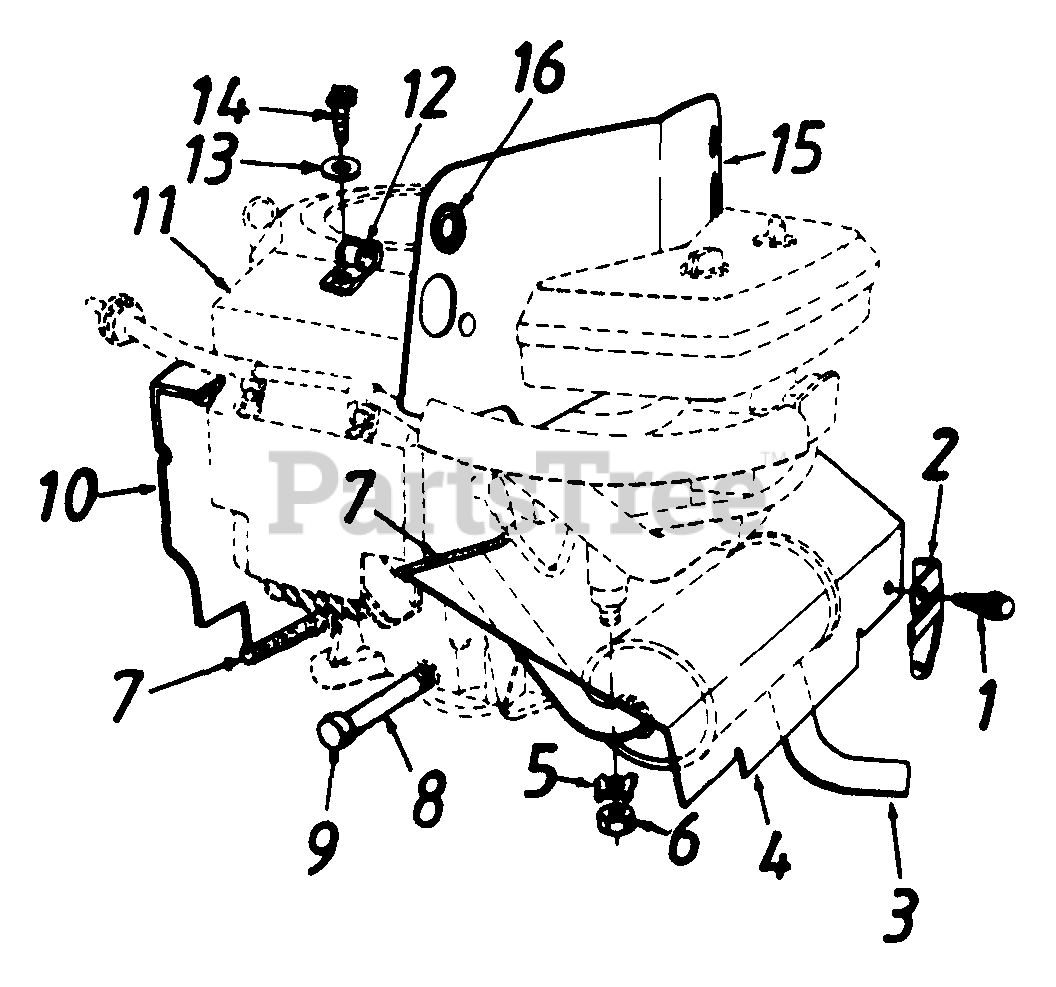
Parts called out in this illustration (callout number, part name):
1	Hex AB-Tap Scr. 1/4 x .62"
3	Muffler
4	Front Heat Shield
5	Spec. L-Wash. 5/16 x .88"
6	Hex Nut 5/16-18 Thd.
7	Trim Strip 12" Lg.
8	Pipe Nipple
9	Oil Drain Cap
10	Rear Baffle (Used on Styles 5, 8 and 9)
11	Engine
12	Clamp
13	Fl-Wash. .188" I.D. x .438"
14	Truss Mach. AB-Tap Scr. #10 x .5" Lg.
15	Heat Shield (Style 6 Only)
16	Rubber Grommet (Used w/Ref. 15)
